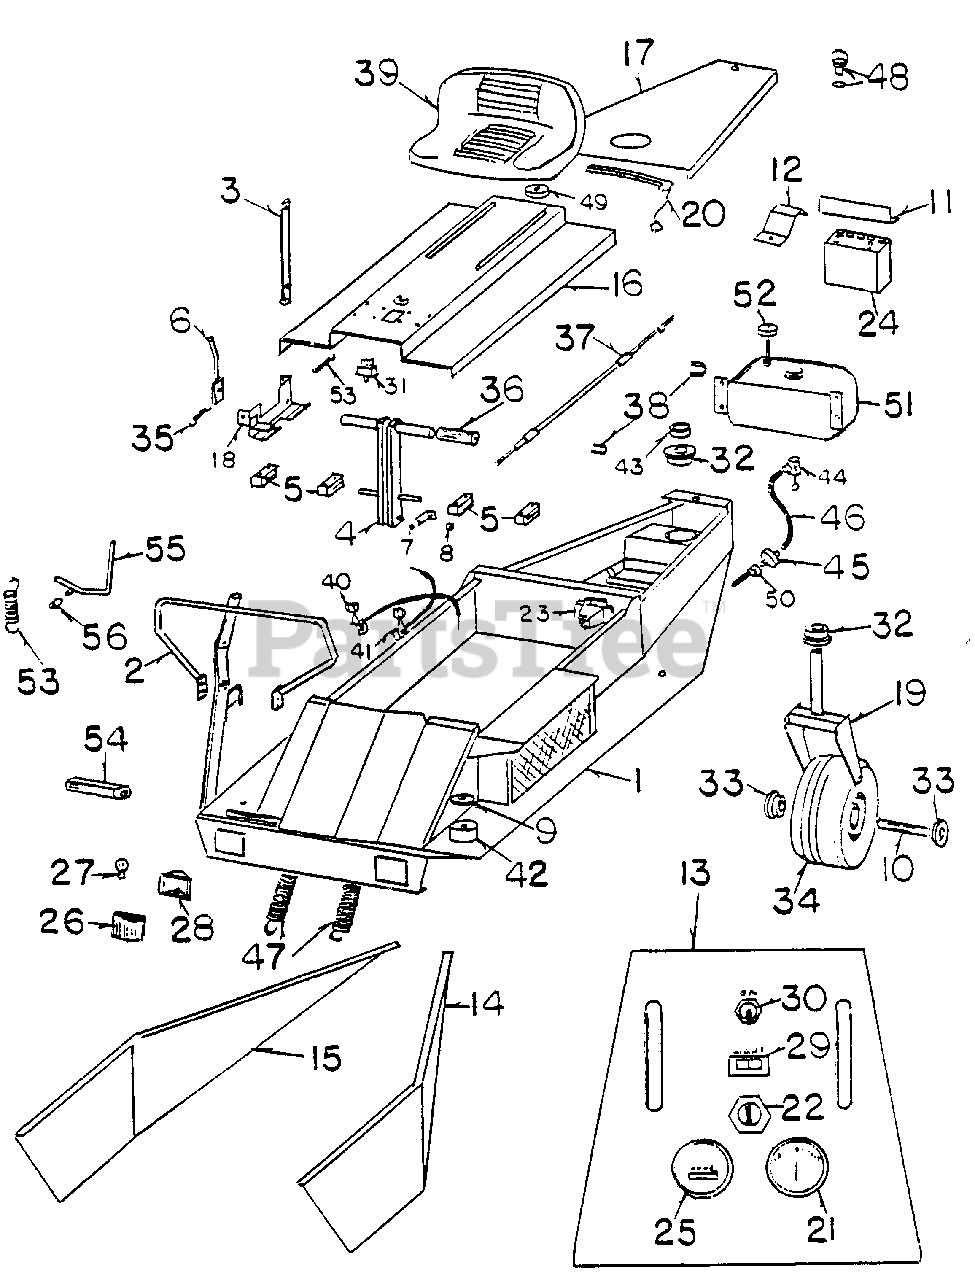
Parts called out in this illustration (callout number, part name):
1	Body
4	Steering Lever
5	Bearing Block, Steering Lever
6	Latch, Lever Lock
7	Steering Cable End
8	Bushing, Steering Cable End
9	Body Hount Uasher
10	Axle, Tail Wheel
11	Hold Down
12	Battery Post Protector
19	Tail Uheel Fork
22	Starter Switch
24	Battery
26	Lens
27	Bulb
29	Light Switch
30	Clutch Switch
32	Bearing, Tail Wheel Housing
33	Bearing, Tail Wheel
34	Tail Uheel Psserbly
35	Spring, Lever Lock
36	Handle Grip
37	Steering Cable
38	Clap
40	Throttle Cable
42	Rubber Body Hount
44	Valve, Fuel Tank
45	Fuel Filter
50	Clap, Fuel Hose
52	Cap, Fuel Tank
55	Brake Loch
56	Tub, Brake Lock 41
